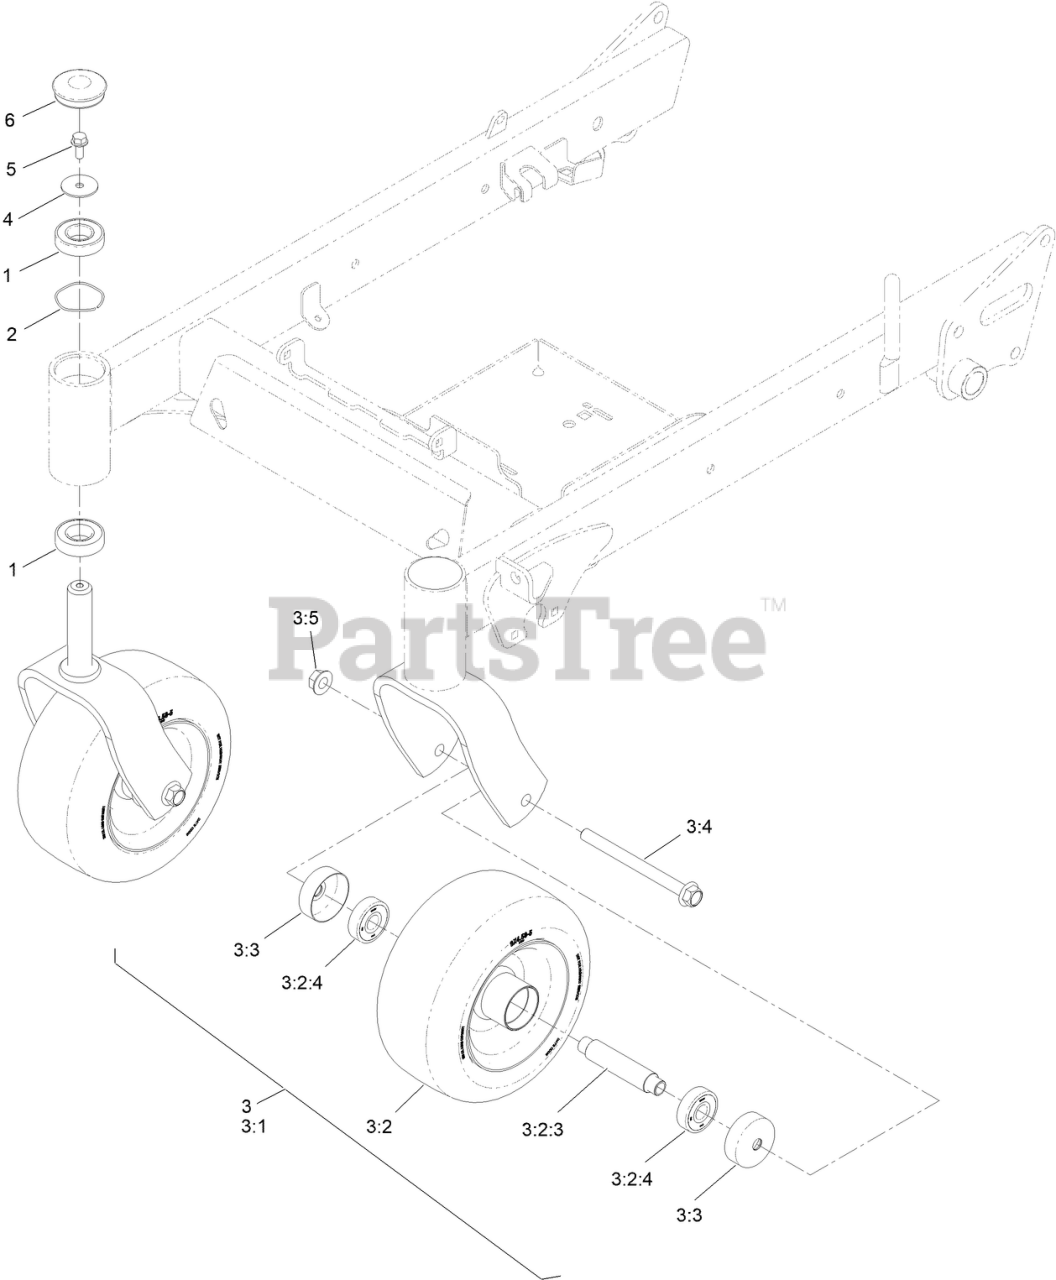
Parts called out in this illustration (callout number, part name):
1	BEARING-BALL
2	SPRING
3	ASM-CASTER FORK W/TIRE
3:1	ASM-CASTER FORK [RED]
3:2	ASM-TIRE WHL SP 9X4.50-5
3:2:3	AXLE-CASTER
3:2:4	BEARING
3:3	GUARD, SEAL
3:4	SCREW-HHF
3:5	NUT-HF
4	WASHER-FLAT
5	SCREW-HHF
6	CAP,GREASE
